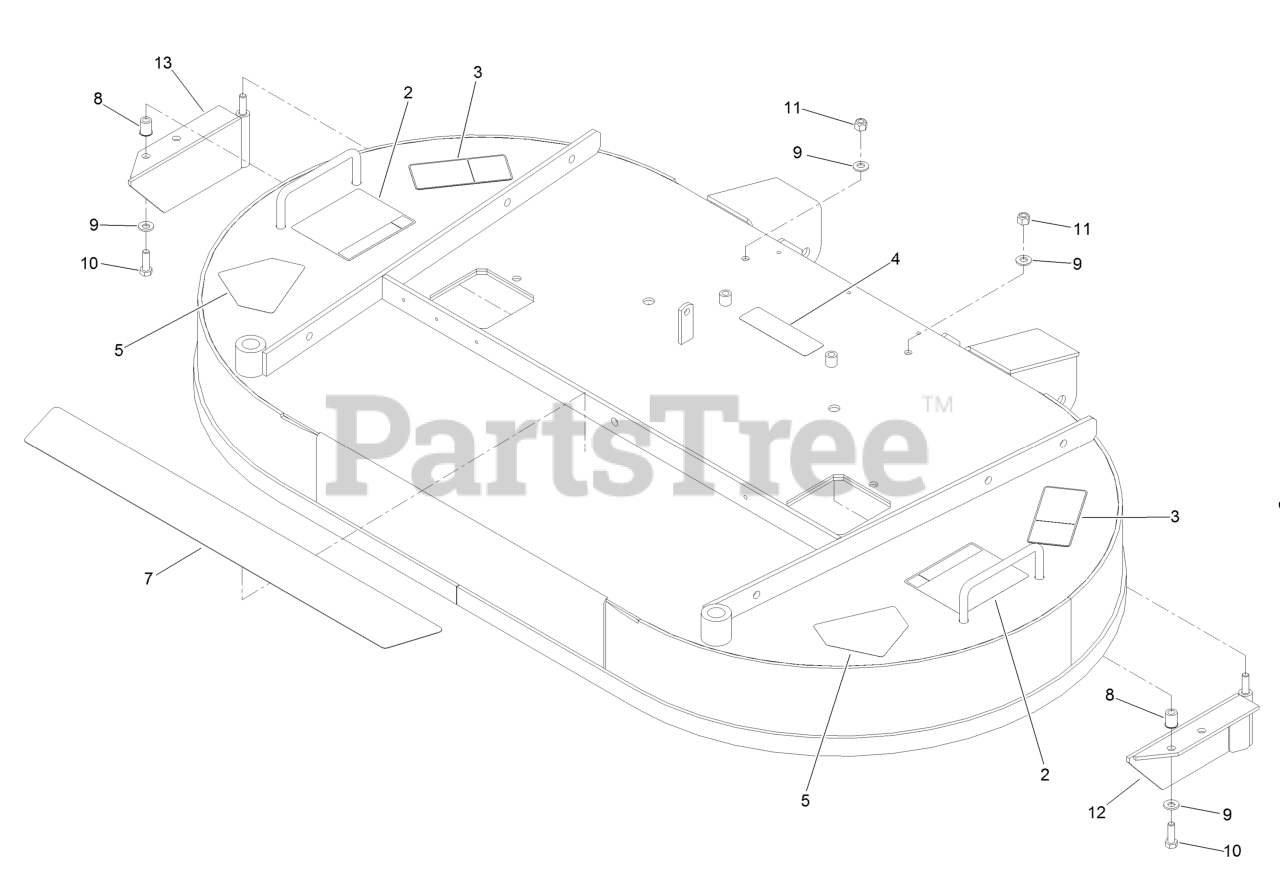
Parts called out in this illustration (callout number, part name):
2	DECAL-HEIGHT ADJUST, CUTT
3	DECAL-TORQUE, BLADE BOLT
4	DECAL-COVER, MISSING
5	DECAL-DANGER
7	PAD-ANTI SKID
8	NUT-CLINCH
9	WASHER-SPRING
10	SCREW-HH
11	NUT-LOCK, NI
12	BAFFLE-LH
13	BAFFLE-RH
